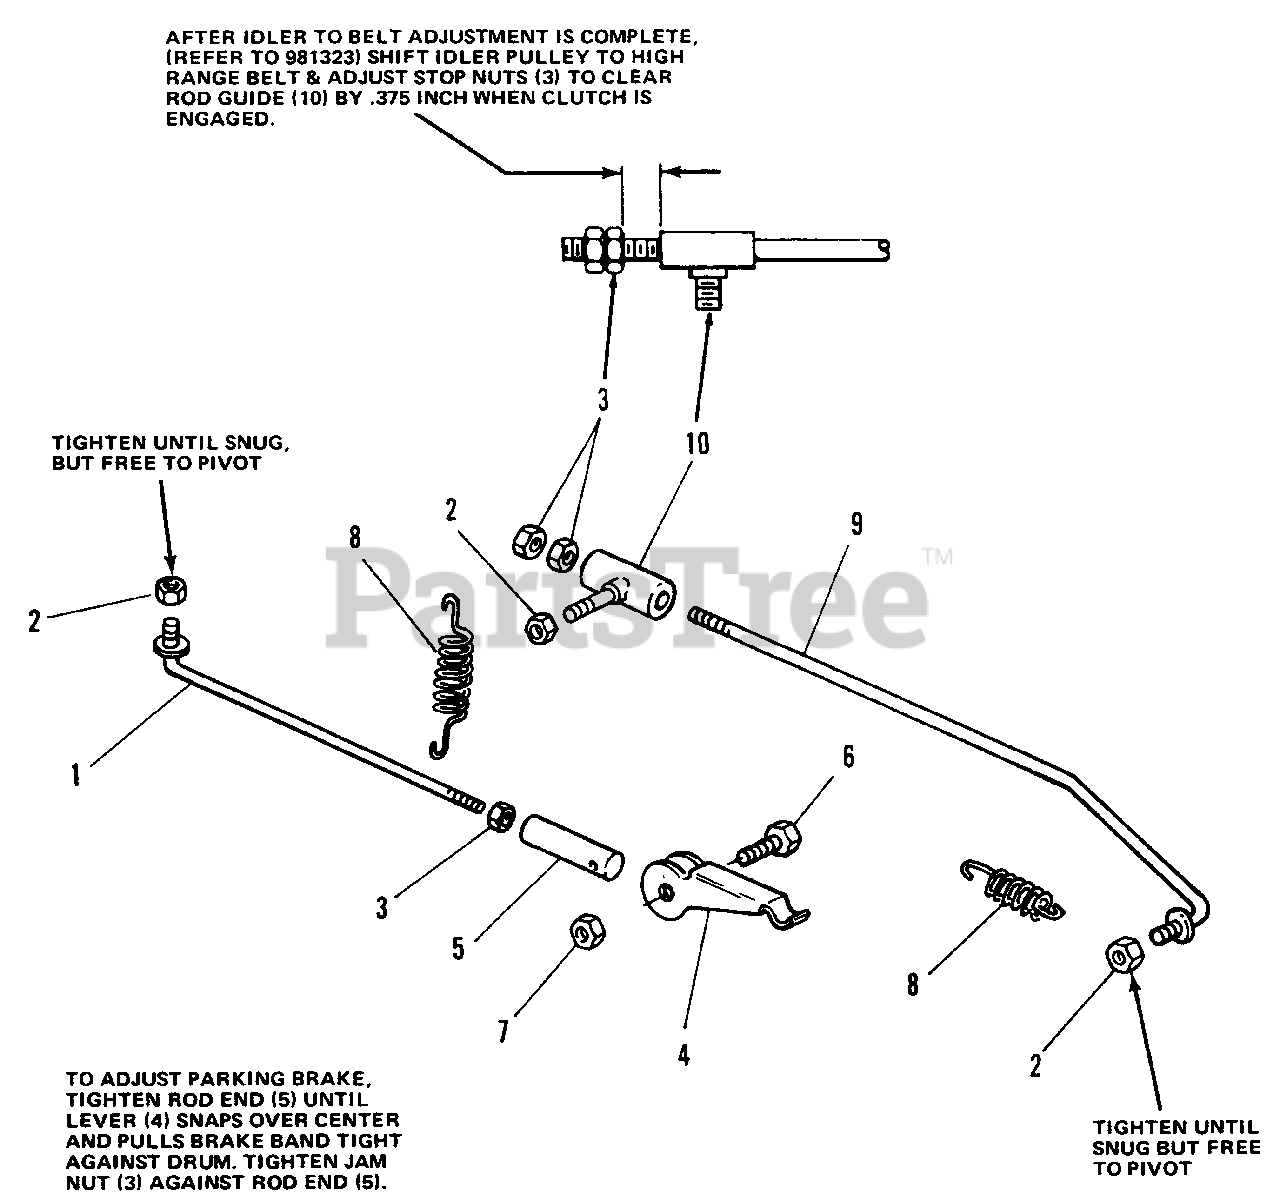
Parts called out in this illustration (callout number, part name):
1	PARKING BRAKE ROD ASSEMBLY
2	LOCKNUT, Hex, .312-18
3	NUT, Hex, Full, .312-18
4	LEVER, Parking Brake
6	CAPSCREW, Hex Hd., .250-20 x 1.00
7	LOCKNUT, Hex, .250-20
9	CLUTCH & BRAKE ROD ASSEMBLY
10	ROD GUIDE ASSEMBLY
